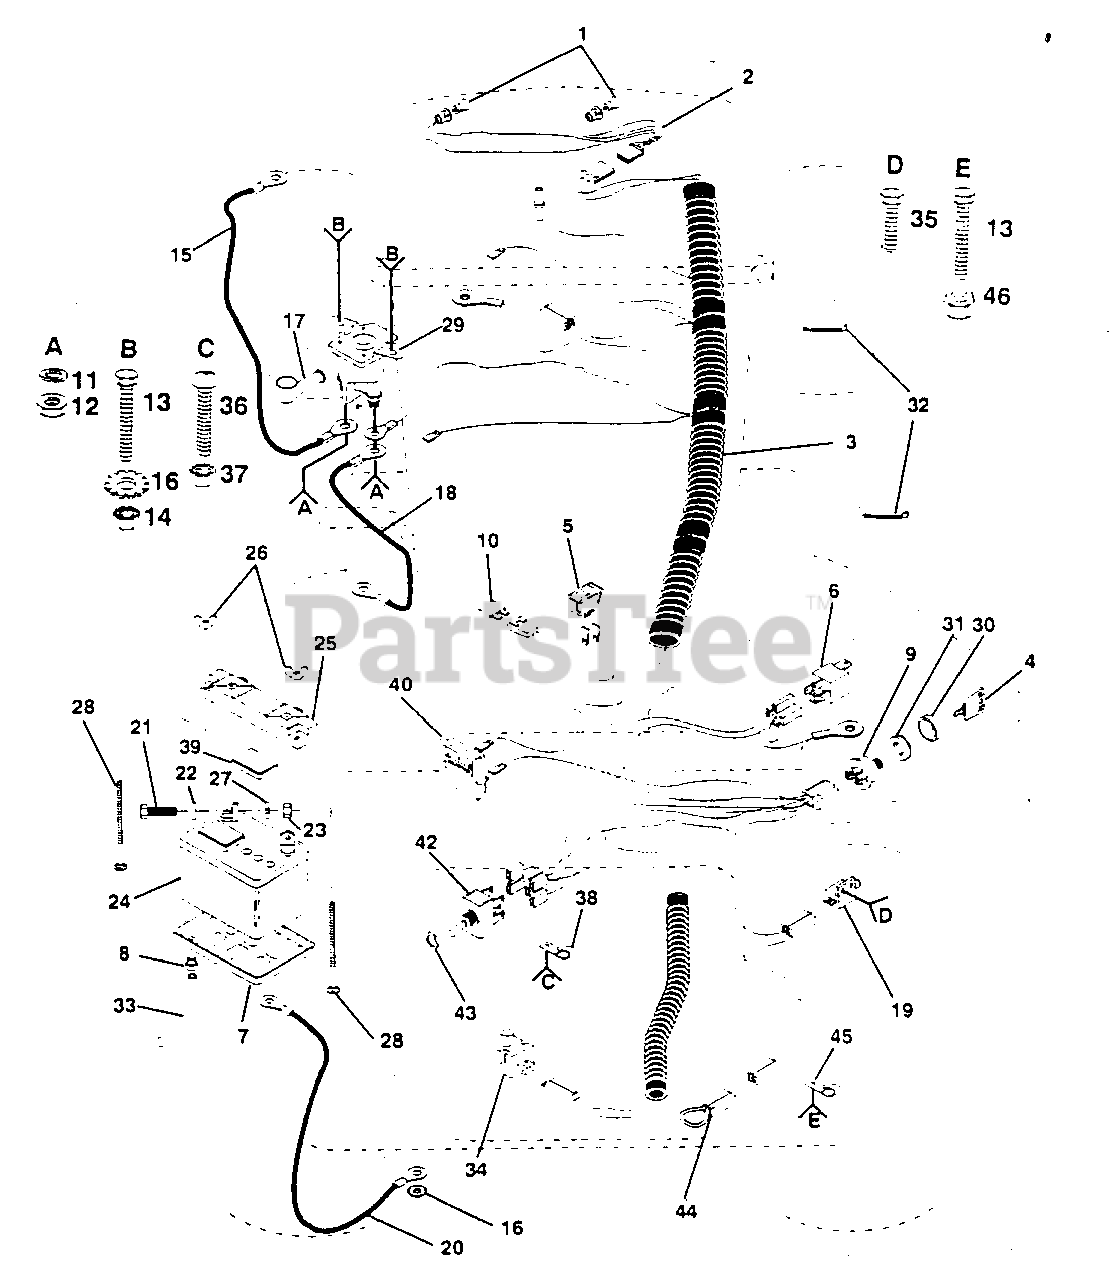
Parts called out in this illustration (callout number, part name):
1	Bulb, Light (AYP part number)
2	Harness, Light Socket (AYP part number)
3	Harness, Ignition
4	Key, Molded (AYP part number)
5	Switch, Light (AYP part number)
6	Relay (AYP part number)
7	Tray, Battery (AYP part number)
8	Clamp, Hose (AYP part number)
9	Switch, Ignition (AYP part number)
10	Fuse (AYP part number)
11	Washer, Lock 1/4 (AYP part number)
12	Nut, Hex Jam 1/4 20 (AYP part number)
13	Bolt, Hex 1/4-20 x 1/2 Grade 5 (AYP part number)
14	Nut, Keps 1/4-20 (AYP part number)
15	Cable Assembly (AYP part number)
16	Washer, Lock, External Tooth 1/4 (AYP part number)
17	Cover, Terminal (AYP part number)
18	Cable, Battery (AYP part number)
19	Switch, Interlock (AYP part number)
20	Cable, Battery (AYP part number)
21	Bolt, Hex 1/4-20 x 3/4 (AYP part number)
22	Washer 9/32-5/8 x 16 Gauge (AYP part number)
23	Nut, Hex 1/4-20 (AYP part number)
24	Battery (AYP part number)
25	Guard, Terminal (AYP part number)
26	Nut, Wing 1/4-20 (AYP part number)
27	Washer, Lock, Heavy Helical Spring (AYP part number)
28	Bolt, Carriage 1/4-20 x 7-1/2 (AYP part number)
29	Solenoid (AYP part number)
30	Bezel, Ignition (AYP part number)
31	Nut, Ignition (AYP part number)
32	Cable Tie (AYP part number)
33	Tube, Battery Tray (AYP part number)
34	Switch, Seat (AYP part number)
35	Screw, Hex Tapping #10-24 UNC x 1/2 (AYP part number)
36	Screw, Slotted Pan Head #10-32 x 1/2 (AYP part number)
37	Nut, Keps #10-32 x 1/2 (AYP part number)
38	Clip, Insulated (AYP part number)
39	Caps, Battery (AYP part number)
40	Ammeter (AYP part number)
42	Switch P.T.O. (AYP part number)
43	Nut, Hex (AYP part number)
44	Loop, Wire (AYP part number)
45	Clip, Wire (AYP part number)
46	Nut, Crownlock 1/4-20 (AYP part number)
